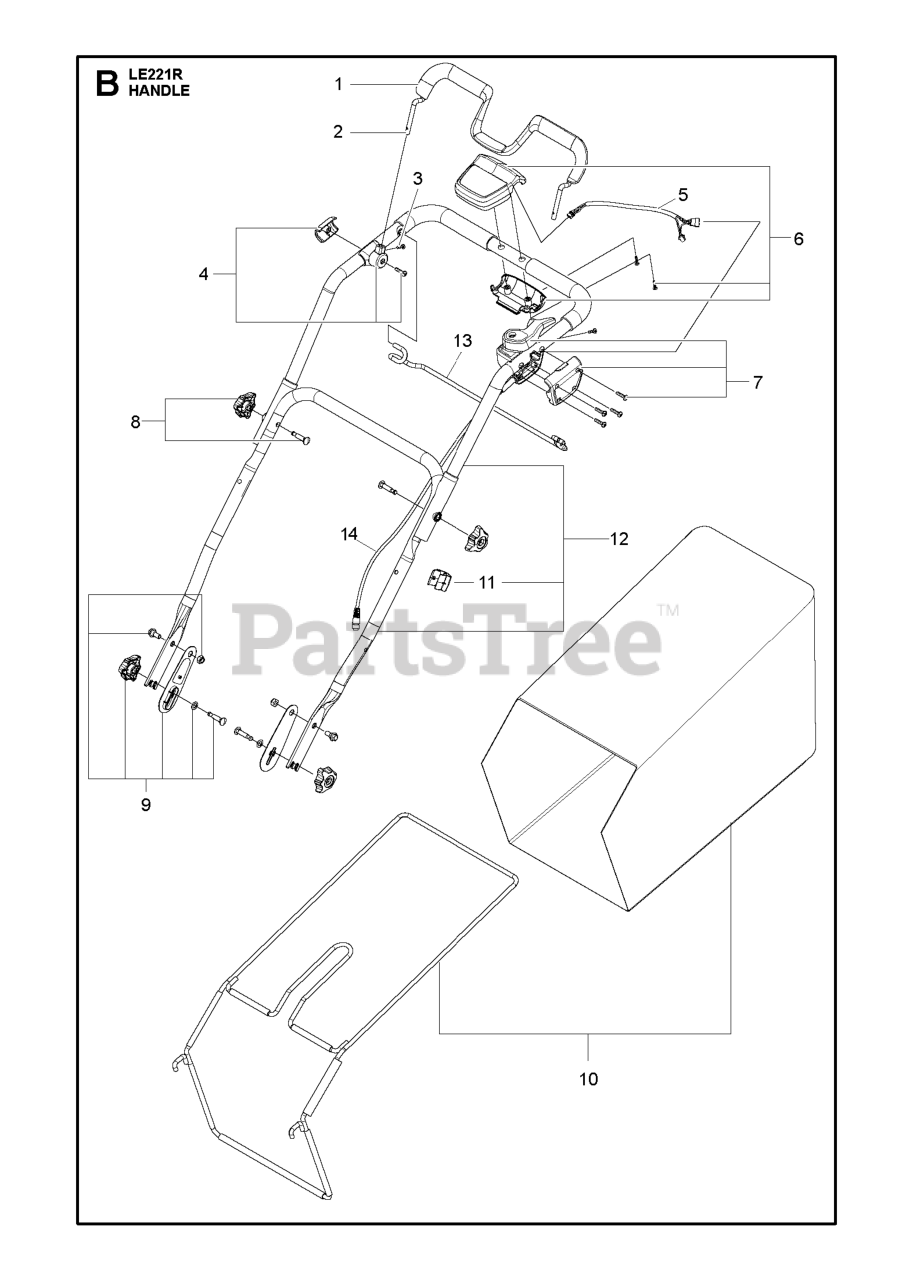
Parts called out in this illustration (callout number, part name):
1	GRIP HANDLE ASSY OPC BAIL
2	BAIL HANDLE ASSY OPC BAIL
3	DRIVE SCREW HANDLE ASSY M4 BAI
4	BAIL ARM ASSY SPARE PART ASSY
5	EXTENSION CABLE CONTROL PANEL
6	CONTROL BOARD ASSY LE221R
7	SWITCHBOX ASSY SPARE PART ASSY
8	KNOB KNOB ASSY UPPER
9	KNOB ASSY LOWER HANDLE SCREW K
10	GRASS BAG ASSY LE121P / LE221
11	CABLE HOLDER HANDLE ASSY
12	HANDLE ASSY
13	BAIL HANDLE ASSY DRIVE BAIL
